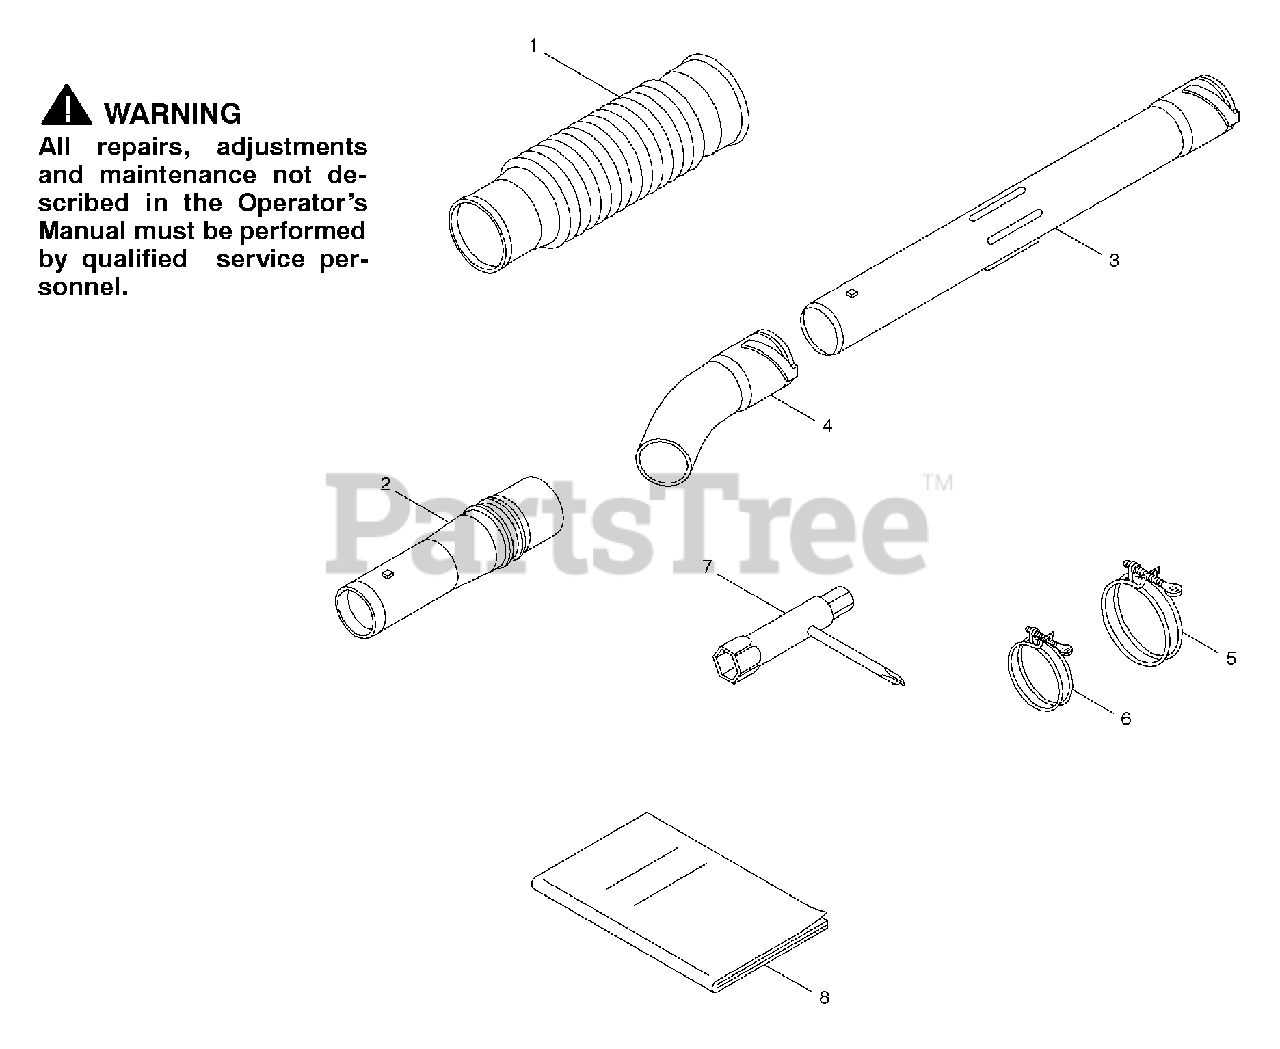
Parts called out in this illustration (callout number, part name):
1	Tube - Flex
2	Tube - Base
3	Tube - Middle
5	Clamp - Wire Lg.
6	Clamp - Wire Sm.
